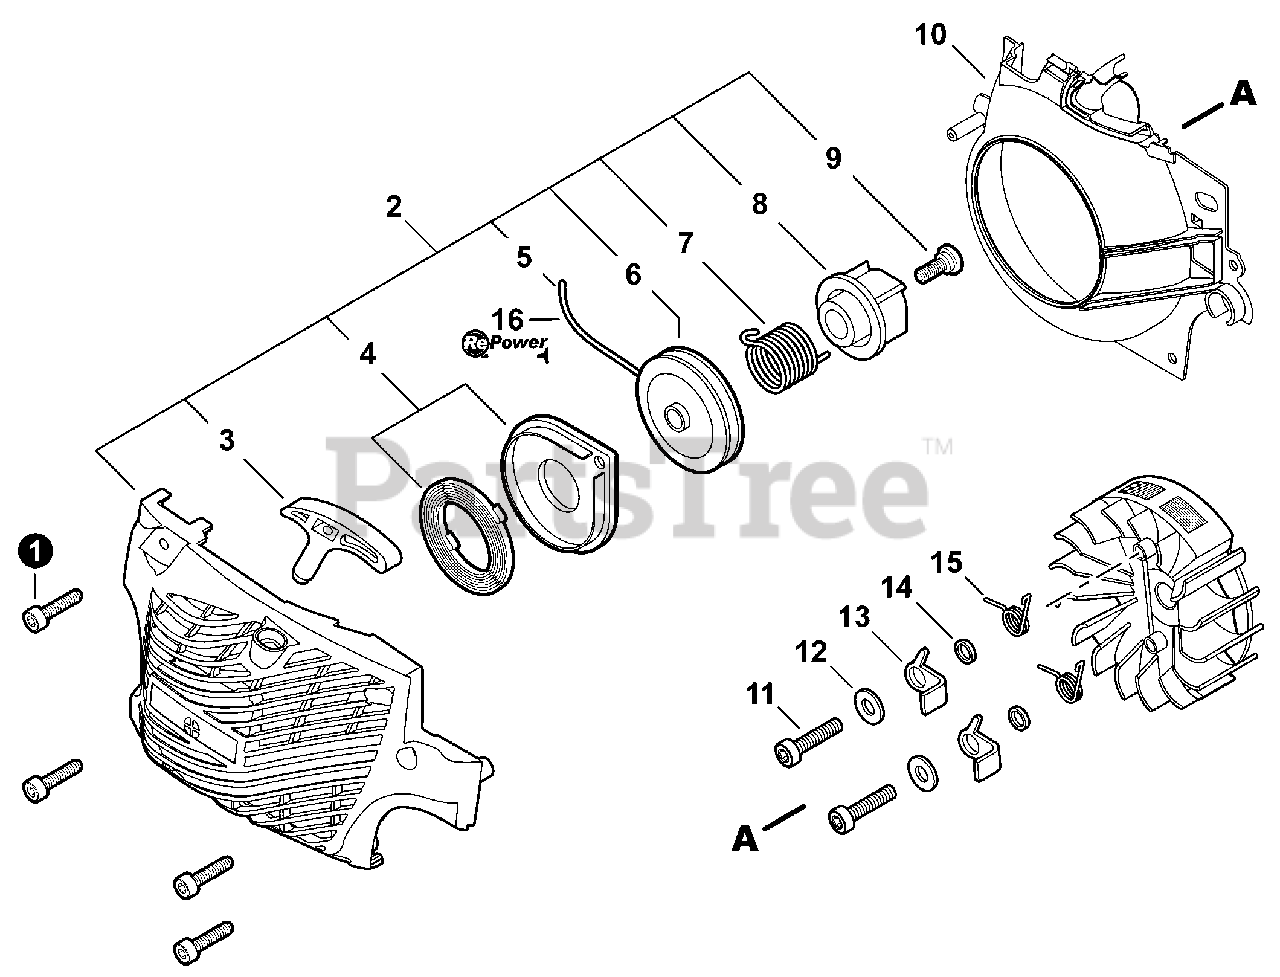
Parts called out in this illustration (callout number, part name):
1	BOLT, TORX 5×20
2	STARTER ASSY, RECOIL
3	GRIP, STARTER
4	SPRING KIT, RECOIL
5	ROPE, STARTER 3.5×900
6	REEL, ROPE
7	SPRING, TORSION
8	PAWL CATCHER
9	SCREW
10	COVER, FAN
11	BOLT 5×14
12	WASHER 5.5×12×0.8
14	SPACER 5.2×8×2.1
15	SPRING, TORSION
16	BULK STARTER ROPE - Ø 3.5 MM×61 M
